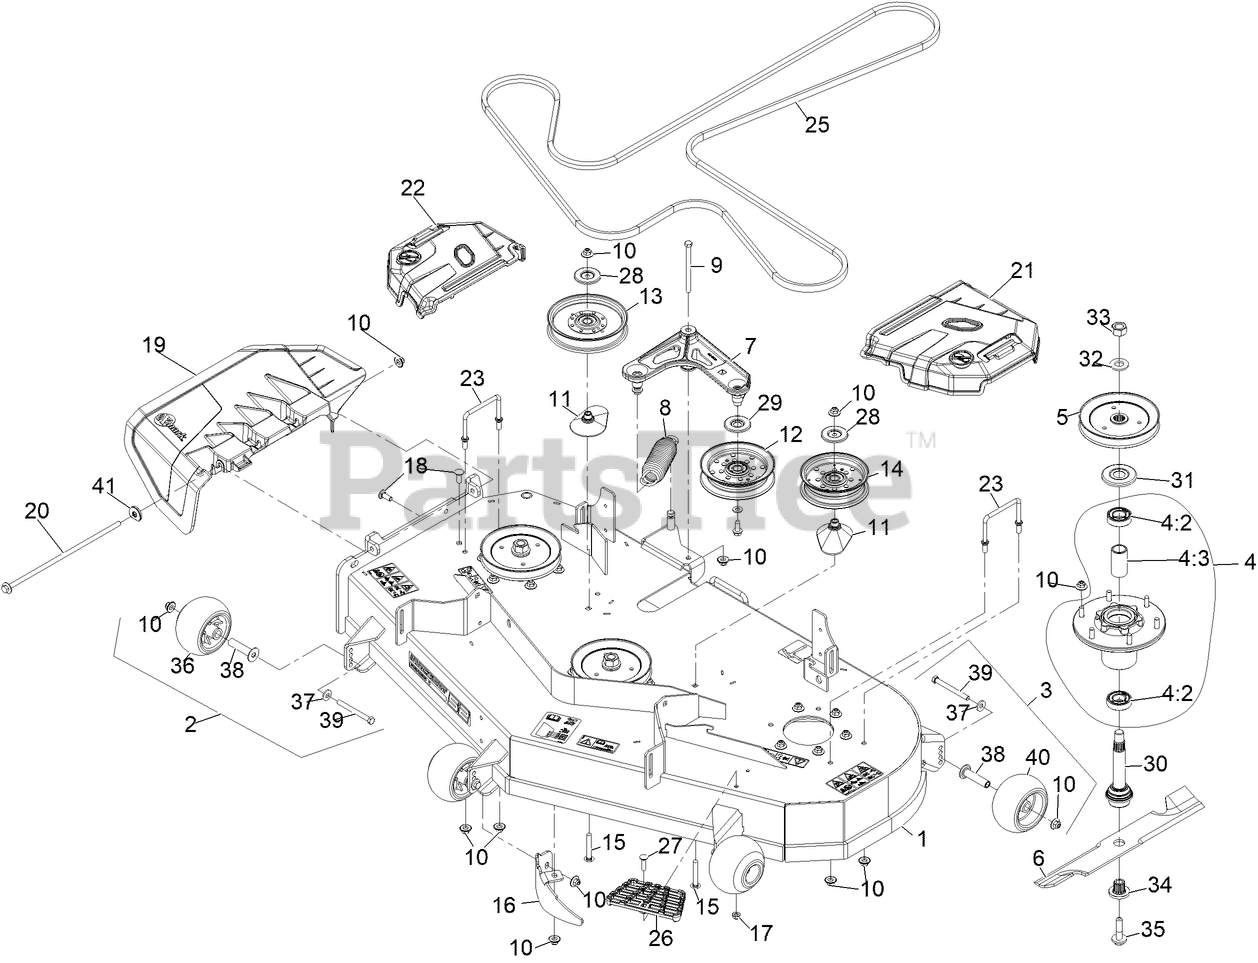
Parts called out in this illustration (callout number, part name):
1	ASM-DECK W/DECALS 524
2	KIT, ANTI-SCALP ROLLER
3	KIT-ANTISCALP ROLLER
4	ASM-CUTTER HSG WITH BEARINGS
4:2	BEARING-BALL
4:3	SPACER-BEARING
5	SHEAVE,BLADE DRIVE 6.50
7	ASM-IDLER ARM W/BEARINGS
8	SPRING-EXTENSION
9	SCREW-HH
10	Nut-Nyloc 3/8-16 Flg
11	SPACER-PULLEY
12	IDLER-PULLEY, FLAT
13	IDLER-PULLEY, FLAT 6.00X1.00
14	IDLER-PULLEY, FLAT 5.00X1
15	SCREW-CARR
16	BAFFLE-DOGLEG, LZ-VT52
17	NUT-HF, NI
18	SCREW-CARR
19	Chute-Deck Discharge
20	Pin, Chute
21	SHIELD, LT
22	SHIELD, RT
23	WIREFORM-COVER
26	STEP-DECK
27	Bolt-Carriage 5/16-18 X 1 1/4
28	SHIELD-DUST
29	SHIELD-GUARD, DUST
30	ASM-SPINDLE AND SEAL
31	GUARD-BEARING, TOP
33	NUT-HEX
34	BUSHING,SPLINED
35	SCREW,SEMS 1/2-20 X 2.19
36	ROLLER-SCALP, ANTI
37	WASHER-BELLEVILLE
38	AXLE, ROLLER
39	SCREW-HH 3/8-16 X 3 3/4 GR 8
40	ROLLER-SCALP, ANTI
41	Retainer, Chute
